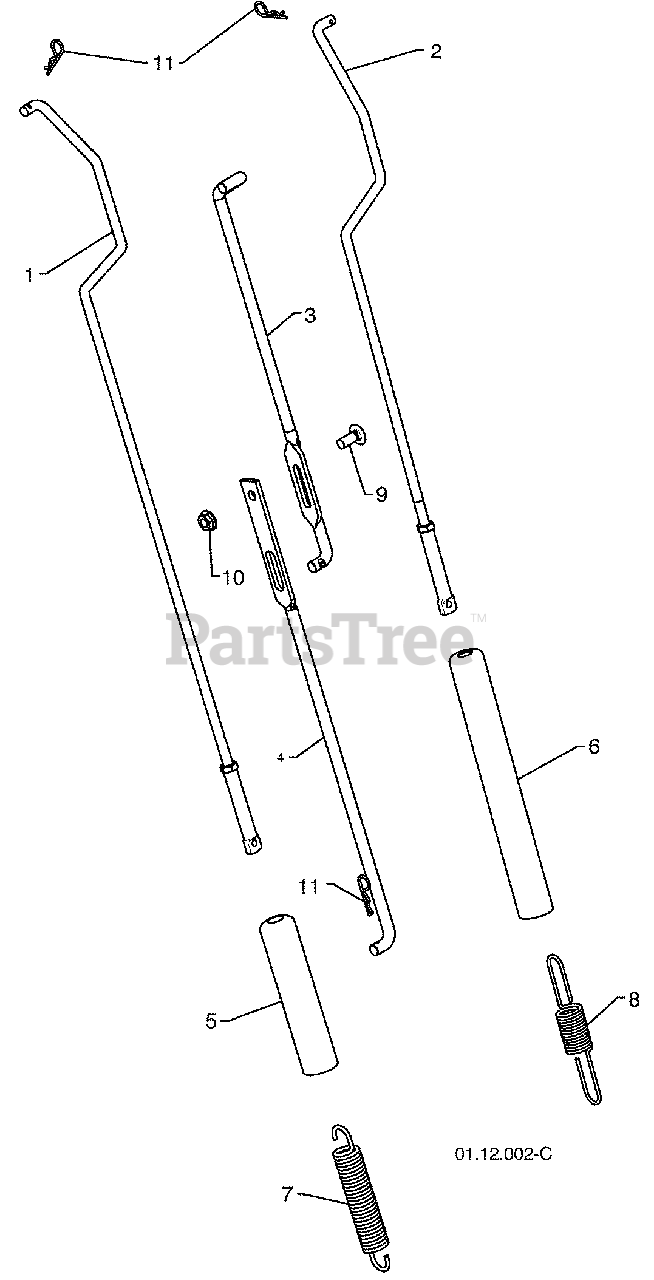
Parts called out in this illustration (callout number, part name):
1	IMPELLER ROD ASSEMBLY
2	TRACTION ROD ASSEMBLY
3	SHIFTER ROD TOP
4	SHIFTER ROD BOTTOM
5	SPRING SLEEVE
6	SPRING SLEEVE
7	IMPELLER SPRING
8	TRACTION SPRING
9	CARRIAGE BOLT 5/16-18 X .750
10	NUT 5/16-18
